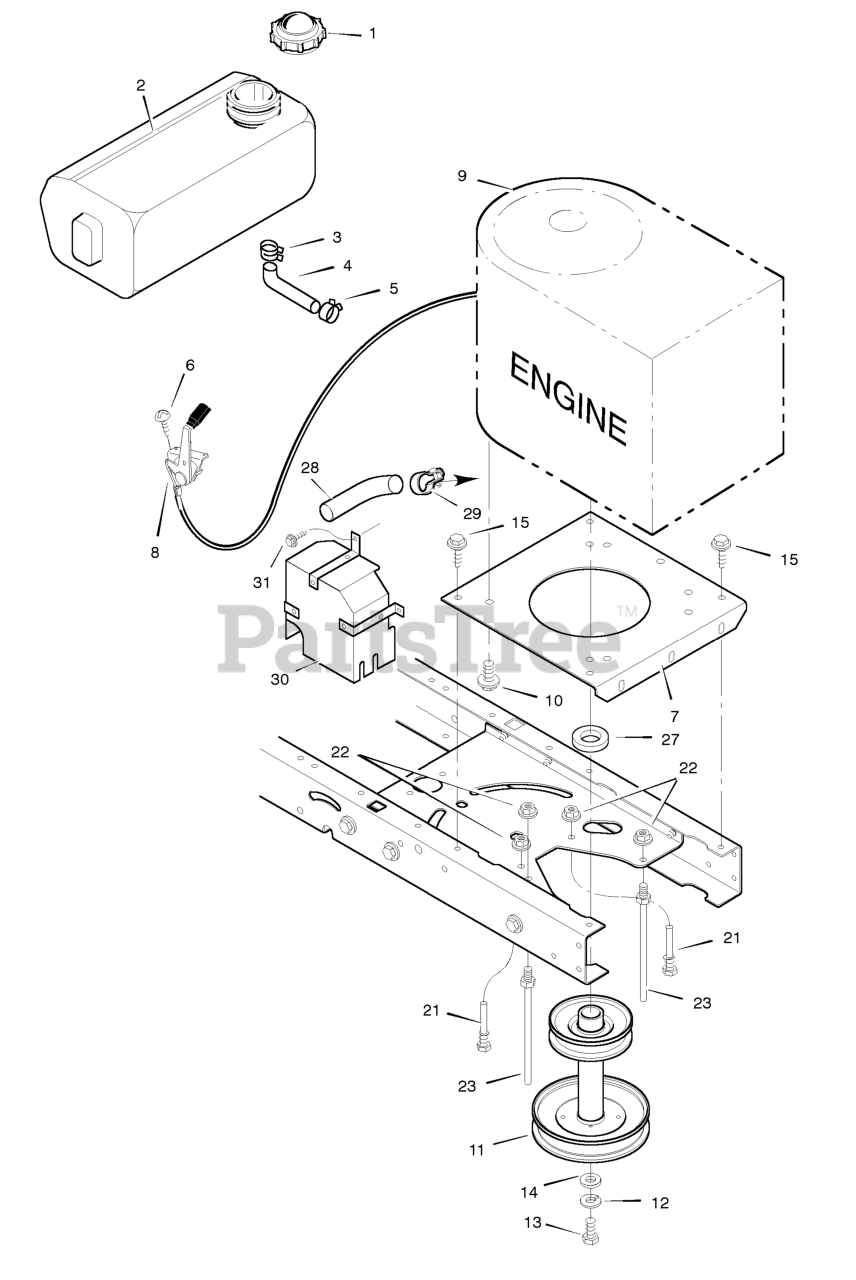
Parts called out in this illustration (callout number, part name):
1	Fuel Cap
2	Fuel Tank
3	Hose Clamp
4	Fuel Line
5	Hose Clamp
7	Plate, Engine
8	Throttle Control
9	Engine
10	Bolt, Engine Mount
11	Stack Pulley Assembly
12	Lockwasher
13	Bolt, Hex
21	Guide, Belt
22	Nut, Flange
23	Guide, Belt
28	Pipe, Exhaust
30	Shield, Heat
